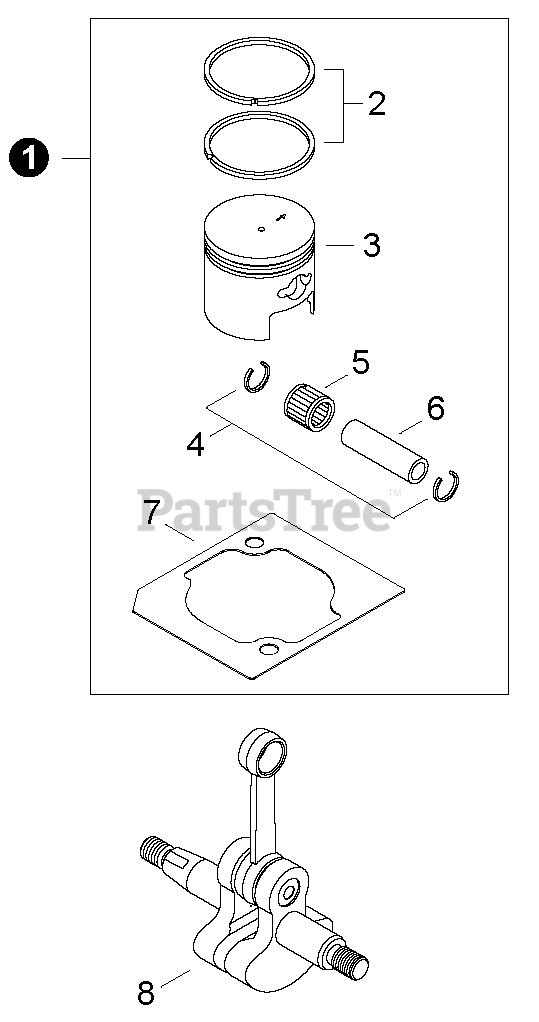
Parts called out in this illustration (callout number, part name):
1	PISTON KIT
2	RING, PISTON
3	PISTON
4	RING, SNAP
5	BEARING, NEEDLE 8
6	PIN, PISTON 8
7	GASKET, CYLINDER
8	CRANKSHAFT ASSY
